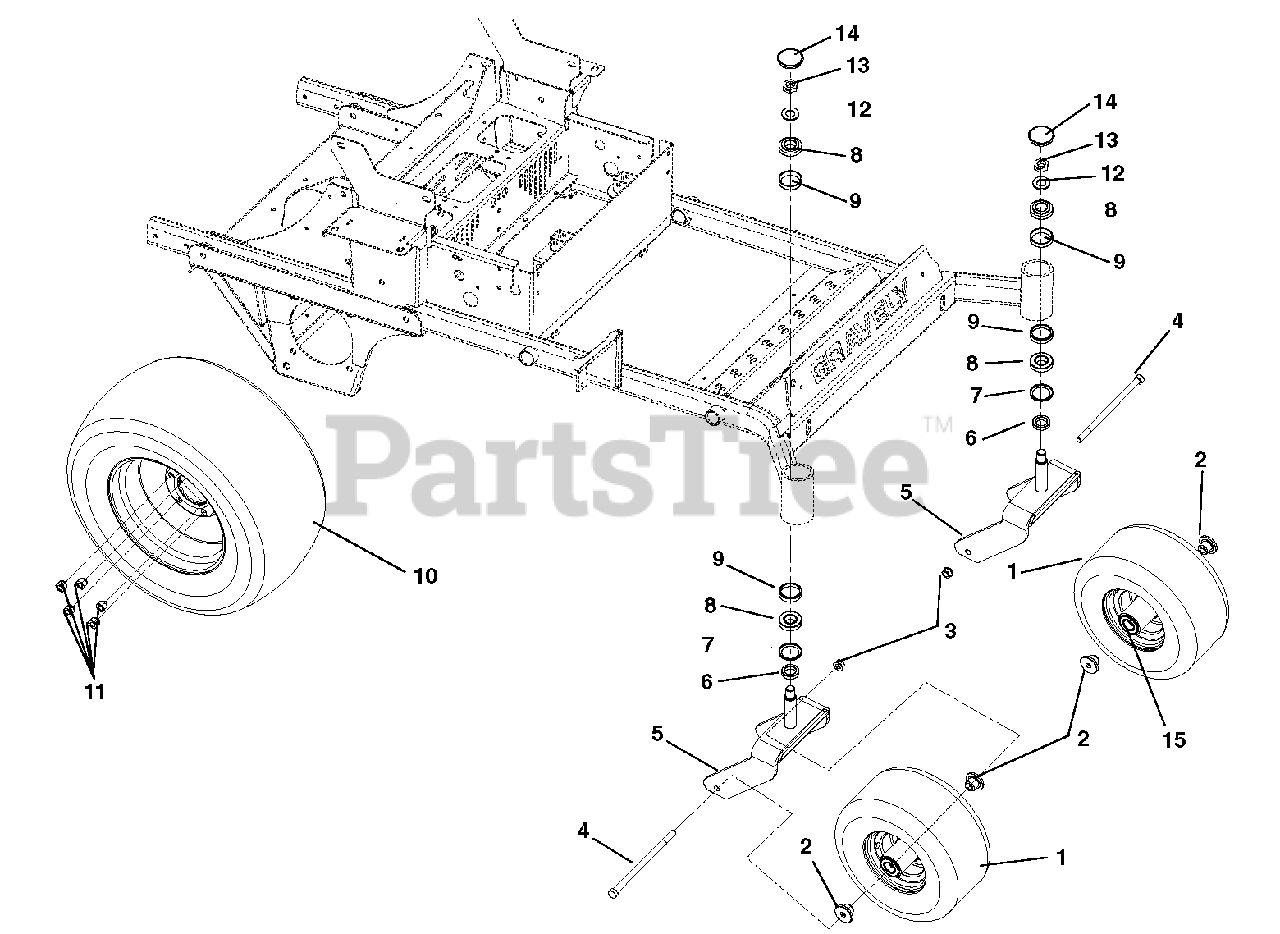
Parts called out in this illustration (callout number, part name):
1	Tire/Wheel Assembly, 15 x 6.00-6
2	Tire, 13 x 6.50-6
3	Spacer, Front Wheel
4	Nut, .50-13 Nyloc Flange
5	Bolt, Hex .50-13 X 9.00 Grade 5
6	Caster Fork Weldment
7	Spacer 1.258 x 1.75 x .550
8	Seal, Oil 1.75 x 2.332 x .312
9	Bearing, Cone 1.25 x .66
10	Bearing, Cup 2.328 x .465
11	Tire/Wheel Assembly, 23 x 10.5-12
12	Tire, 23 x 10.00-12
13	Nut, Wheel .50-20 13/16 Across Flats Automotive Type
14	Washer, Flat Steel .812 x 2.00 x .148
15	Nut, Jam Center-Lock .75-16
16	Cap, Dust
17	Bearing, 25MM ID x 52MM OD x 15MM
